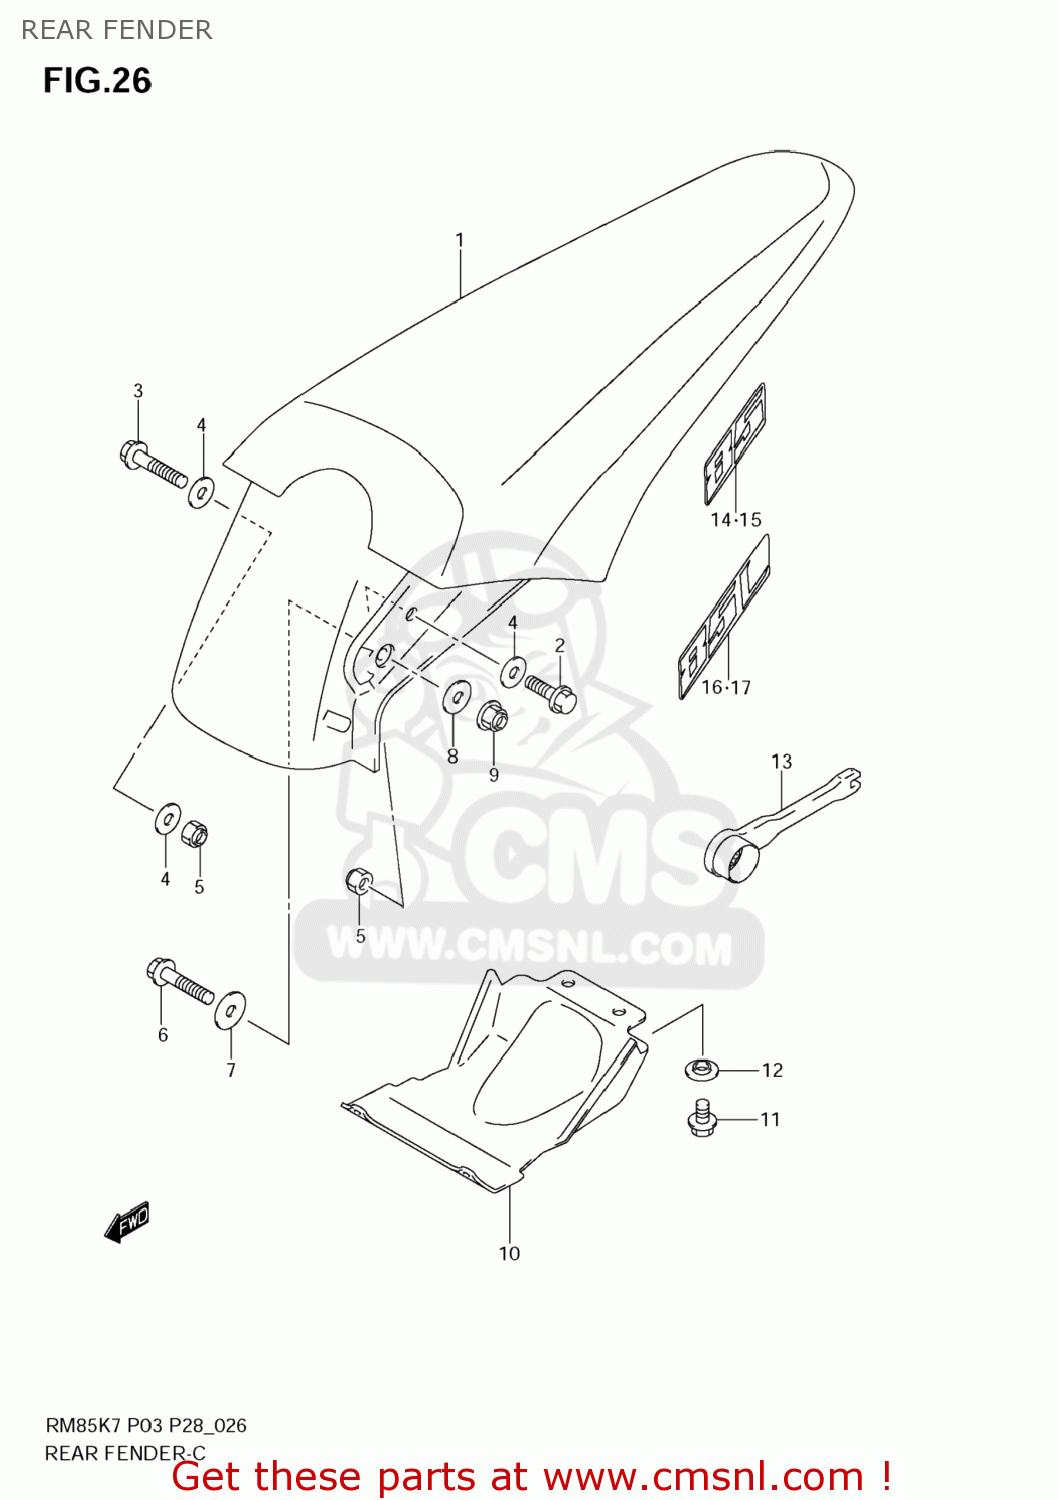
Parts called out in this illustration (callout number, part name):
1	FENDER,RR
2	BOLT,6X20
3	BOLT(6X30)
4	WASHER(6.5X20X1.2)
5	NUT
6	BOLT(6X30)
7	WASHER(6.5X26X2.3)
8	WASHER(6.5X18X1.6)
9	NUT
10	MUDGUARD,RR FENDER FR
11	BOLT
12	WASHER
13	SPARK PLUG WRENCH(21 & 5.8)
14	EMBLEM,RR FENDER,R
15	EMBLEM,RR FENDER,L
16	EMBLEM,RR FENDER,R
17	EMBLEM,RR FENDER,L
